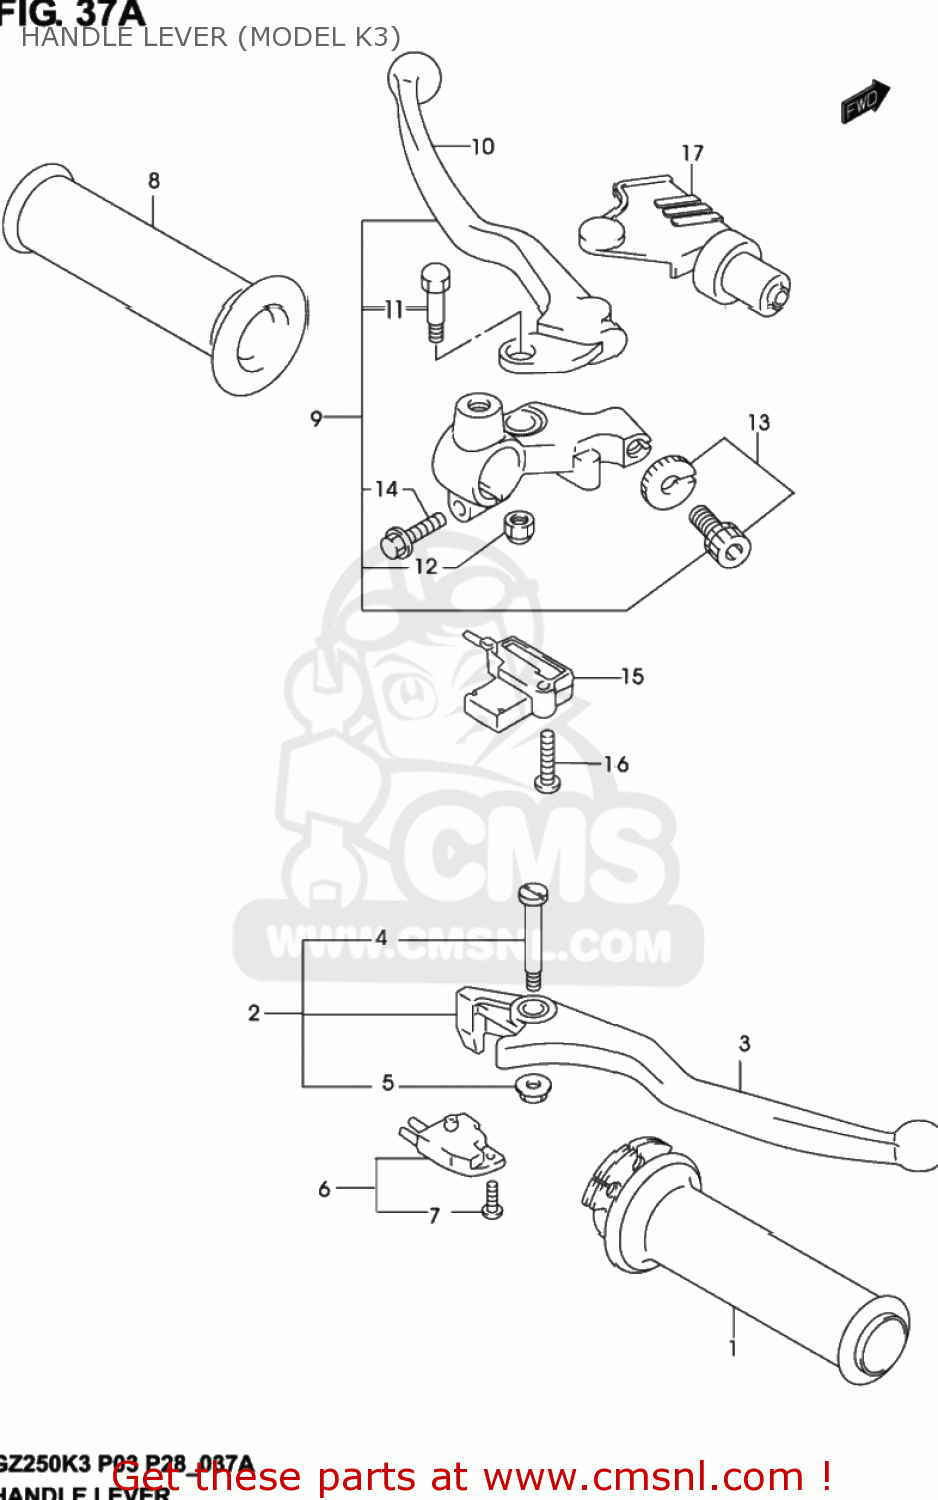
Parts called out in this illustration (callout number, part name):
1	GRIP, THROTTLE
2	LEVER ASSY, BRAKE
3	GRIP, BRAKE
4	BOLT, PIVOT
5	NUT
6	SWITCH ASSEMBLY,STOP
7	SCREW
8	GRIP,LH
9	LEVER ASSY, CLUTCH
10	LEVER, CLUTCH
11	BOLT, PIVOT
12	NUT
13	ADJUSTER SET, WIRE
14	BOLT
15	SWITCH,CLUTCH
16	SCREW
17	COVER,CLUTCH LEVER
